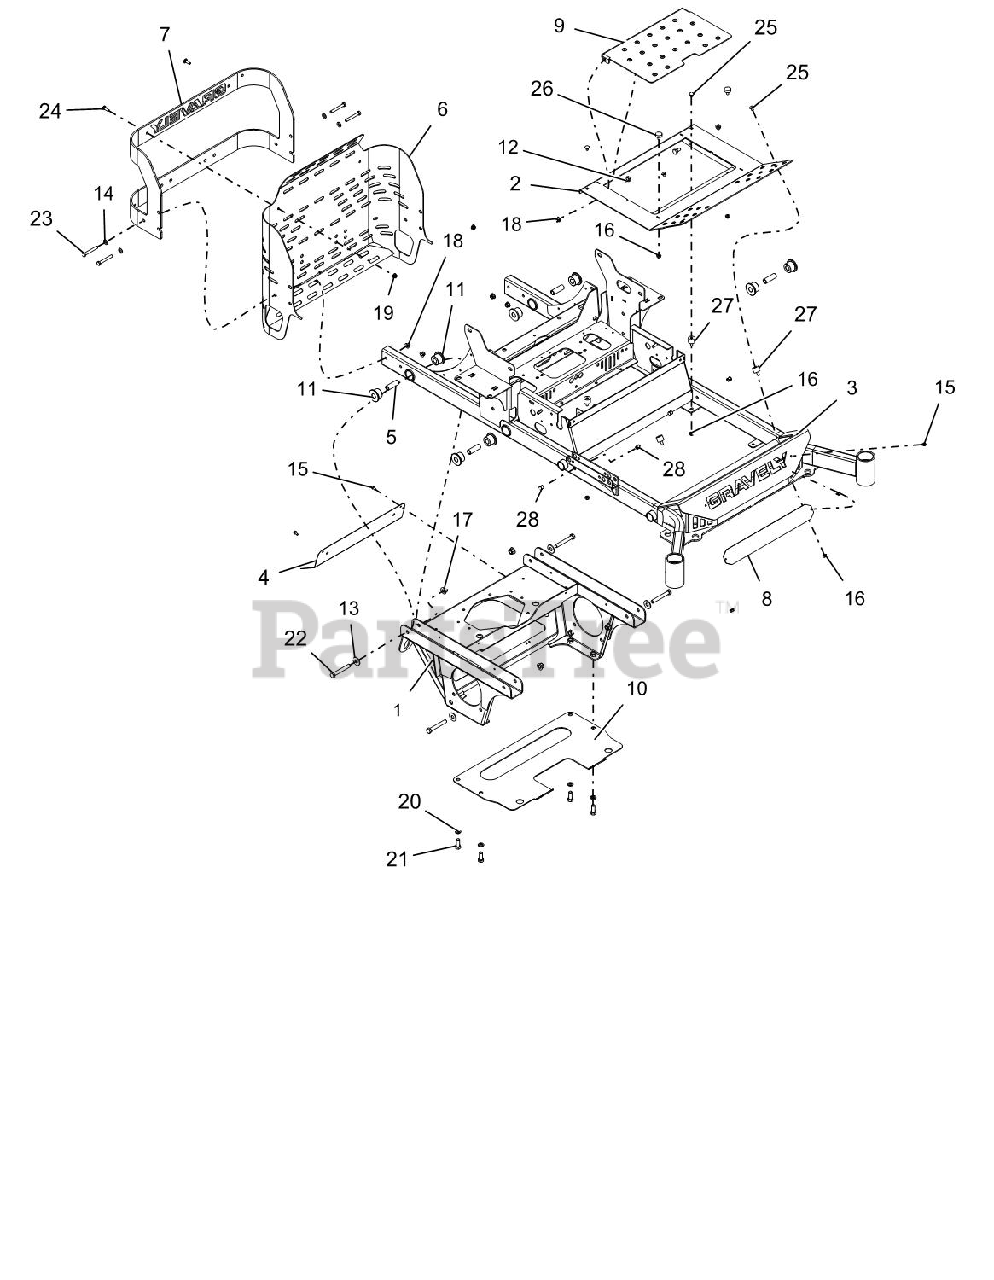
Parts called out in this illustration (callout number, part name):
1	WLDMT, PT200/400 AXLE/ENG FRAME
2	FOOTPLATE WLDMT W/SAFETY DECAL
3	WLDMT, 52-66" PT400 MAIN FRAME-RED
4	SHIELD, MUFFLER HEAT
5	SPCR, .50 X .75 X 2.23 YZ
6	WLDMT, PT200 REAR BUMPER (BLACK)
7	REAR BUMPER W/SAFETY DECALS-GAS
8	PLATE, BUMPER LOGO BACKING-BLACK
9	PANEL, INSPECTION
10	PLATE-TRANSMISSION SKID-RED
11	BSHG, FLANGE .750 X 1.510 X 1.130 X 2.000
12	BLT, SHLDR EP .38-16X.30 HEX YZ
13	WSHR-FL-STL.563X1.38X.109YWZC
14	WSHR-FL-STL.406X.812X.065 YWZ
15	SCR-TAP .25-20X.50 HWH TR YWZ
16	@NUT-SPNLK-FLG .312-18 YWZC
17	NUT-LK-NYL-FLG .50-13 YWZC
18	NUT-LK-NYL-FLG .38-16 YWZC
19	NUT-LK-NYL-FLG .31-18 YWZC
20	WSHR-LK .50X.125 REG YWZC
21	BLT-HEX .50-13X1.25 GR5 YWZC
22	BLT-HEX .50-13X3.50 GR5 YWZC
23	BLT-HEX .38-16X2.75 GR5 YWZC
24	BLT-RDHDSQSHNK .31-18X1.00 G5YWZC
25	BLT-RDHDSQNK .31-18X.50 G5 YWZC
26	BUMPER, RUBBER
27	BUMPER, STUD MOUNTED W/FEMALE INSERT
28	PLUG, HOLE .500
